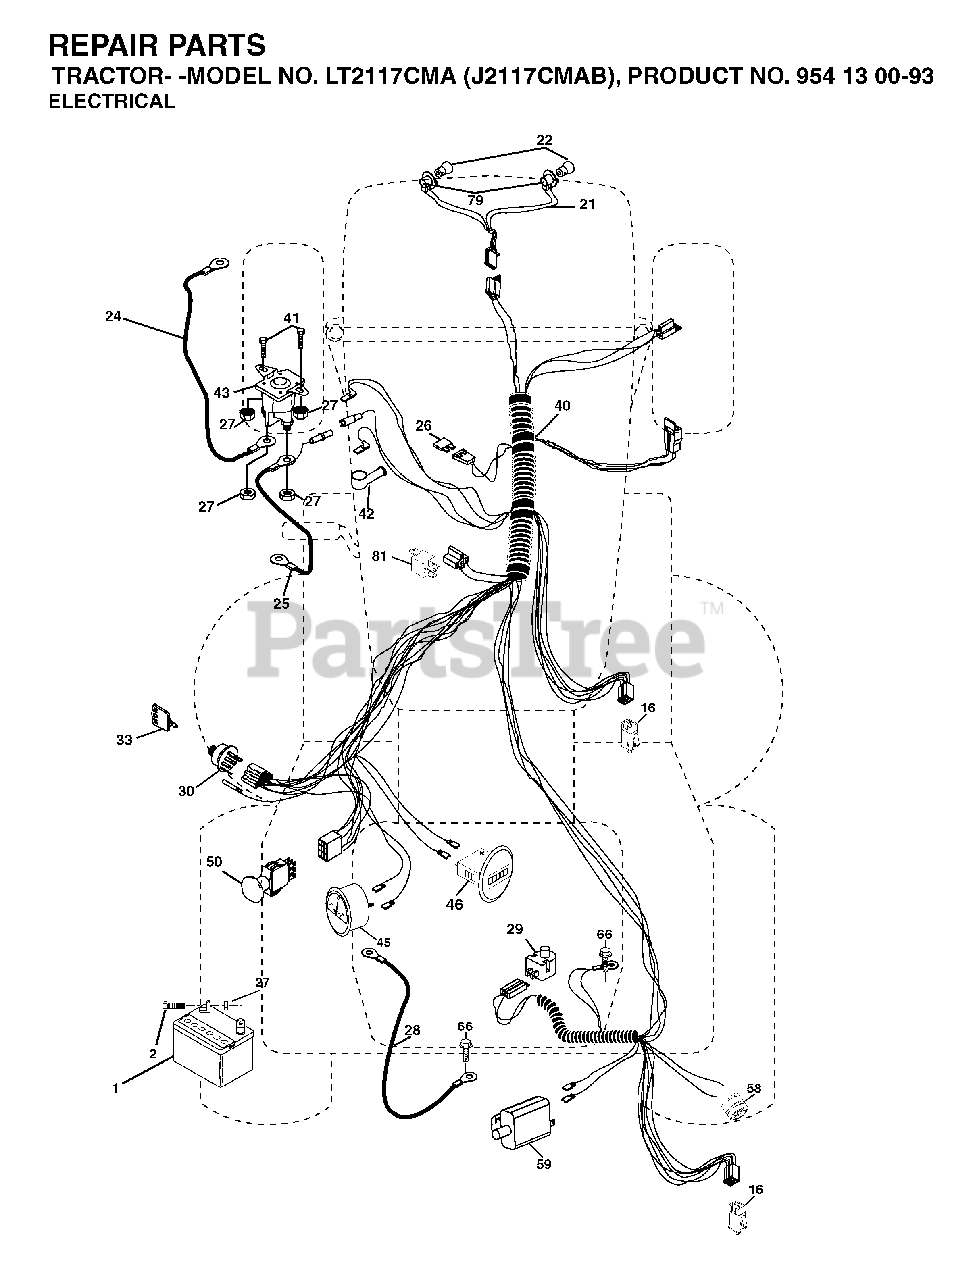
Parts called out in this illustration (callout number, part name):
1	REPL BY 532 12 38-99
16	SWITCH INTERLOOK PUSH-IN
21	HARNESS.W/LIGHT SOCKET
22	LIGHTBULB
24	BATTERY CABLE GT
25	CABLE BATTERY
26	FUSE 20AMP
27	NUT
28	CABLE GROUND
29	PLUNGER SWITCH (COLOR:OLIVE)
30	IGNITION SWITCH
33	KEY MLD GEN DELTA
42	TERMINAL COVER
43	SOLENOID
46	HOURMETER SNAP-IN
50	PTO SWITCH
58	BUZZER
79	BULB HOLDER ASM.
81	RELAY.ASSY.T
